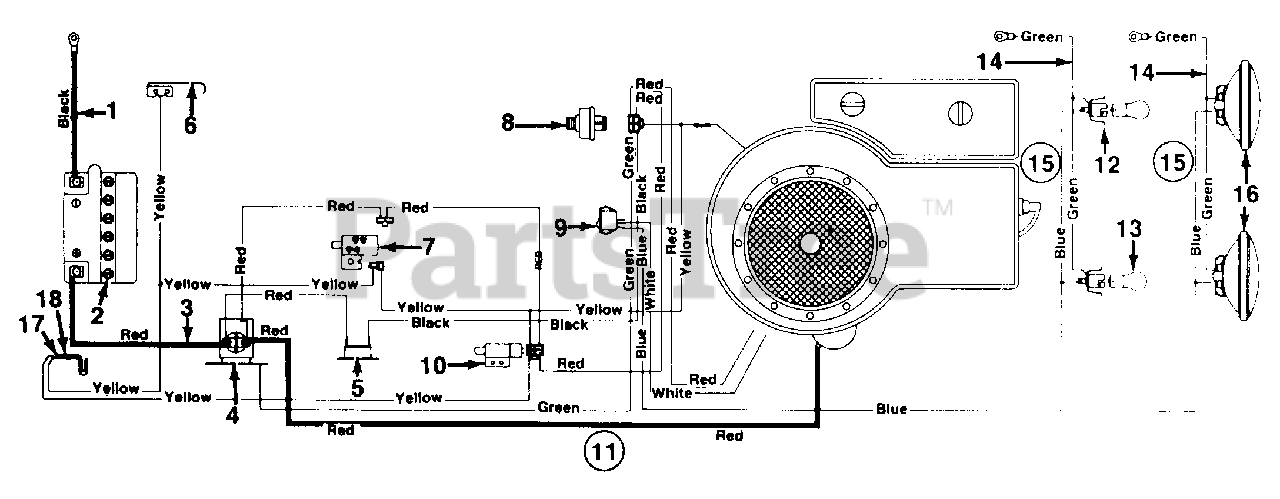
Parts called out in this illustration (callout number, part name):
1	Ground Wire
2	Battery
3	Electric Wire - 8.0" Lg.
4	Solenoid
5	Circuit Breaker
6	Spring Switch (Reverse)
7	Safety Switch (Deck)
8	Ignition Switch
9	Light Switch
10	Safety Switch (Clutch)
11	Harness (B&S)
12	Socket (Sq. Headlights)
13	Bulb (Sq. Headlights)
14	Ground Wire
15	Headlight Harness
16	Headlight (Round)
17	Safety Switch (Seat)
18	Safety Switch (Seat)
